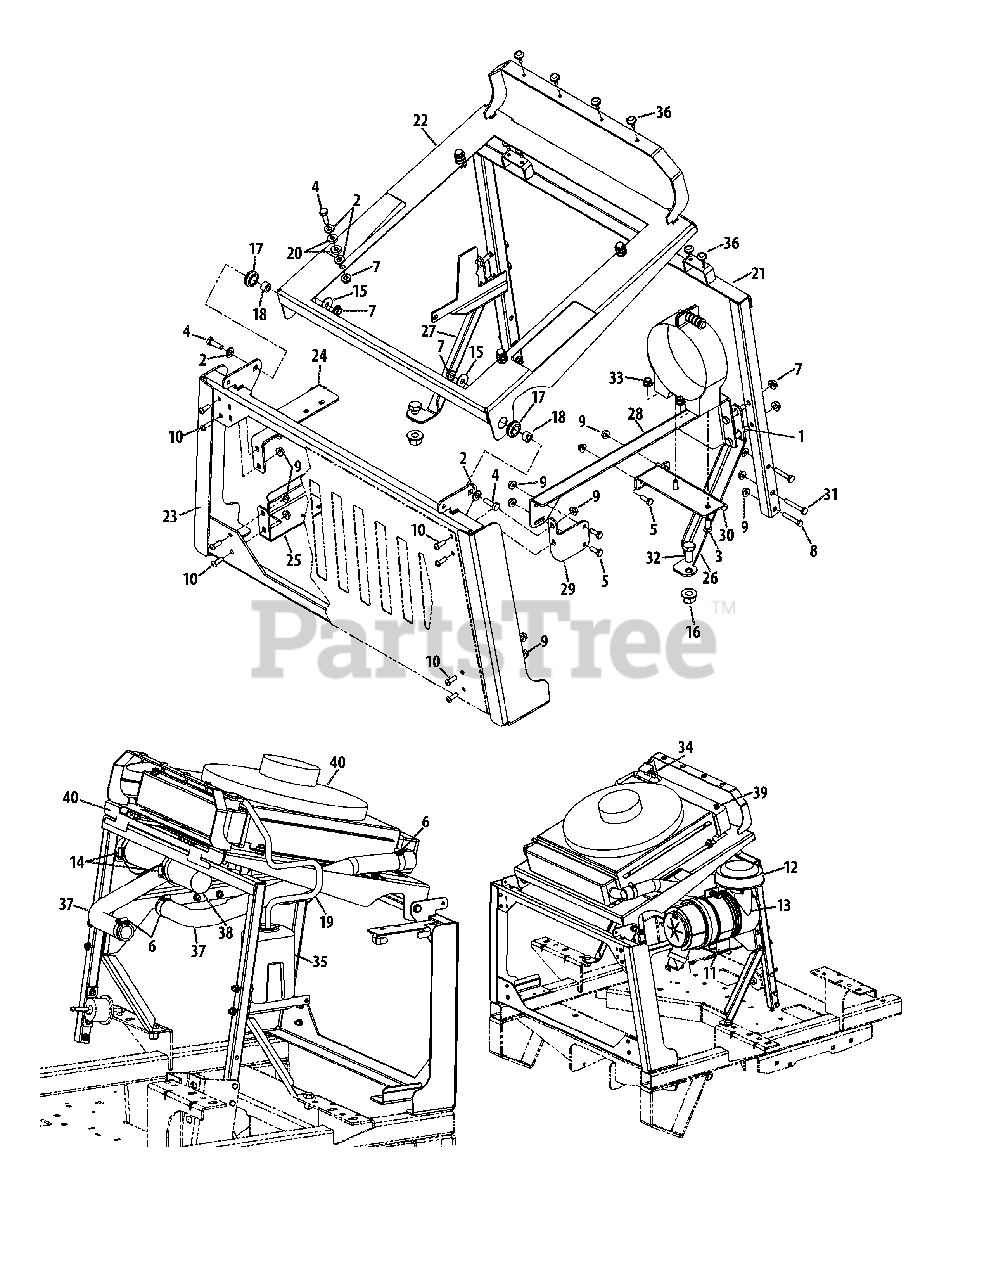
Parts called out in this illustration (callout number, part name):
1	Hex Screw, 5/16-18 x 1.75
2	Washer, .344 x .688 x .063
3	Hex Screw, 5/16-18 x .750
4	Hex Screw, 5/16-18 x 1.00
5	Hex Screw, 1/4-20 x .750
6	Hose Clamp
7	Flange Counter Lock Nut, 5/16-18
8	Hex Screw, 1/4-20 x 1.50
9	Flange Top Lock Nut, 1/4-20
10	Cap Screw, 1/4-20 x .750
11	Air Cleaner Mounting Band
12	Air Cleaner Inlet Hood
13	Air Cleaner Assembly
13	Air Filter
13	Canister, Air Cleaner
13	Cap, Air Cleaner
13	Valve, Dust Ejector
13	Hose Air Cleaner, 2" ID, 10" Length
14	Hose Clamp
15	Washer, .313 x 1.06 x .062
16	Flange Top Lock Nut, 1/2-13
17	Grommet, .62 x 1.13 x 1/8
18	Spacer, .357 x .625 x .375
19	Radiator Hose, 1/4 x 27
20	Washer, .280 x .690 x .180
21	Front Radiator Mount
22	Radiator Mount Plate
24	Hydro Cooler Upper Mount Bracket
25	Hydro Cooler Lower Mount Bracket
26	RH Radiator Support Bracket
27	LH Radiator Support Bracket
28	Air Cleaner Support Bracket
29	Air Cleaner Support Bracket
30	Air Cleaner Mount Bracket
31	Hex Screw, 1/4-20 x 1.75
32	Hex Screw, 1/2-13 x 1.00
33	Flange Lock Nut, 5/16-18
34	Hose Clamp, .490
35	Coolant Over-Flow Container
36	Rubber Bumper, .62 x .22
37	Hose, Radiator RH, 29.50"
37	Hose, Radiator LH, 26.50"
37	Hose, 1-1/8" ID, 25 feet Length
38	Hose Air Cleaner, 2" ID, 10" Length
38	Flexible Reinforced Hose 2" ID
39	Pipe Plug, 1/8-27
40	Radiator, Complete
40	Fan assembly, Diesel
40	Debris Screen
40	Radiator Cap
